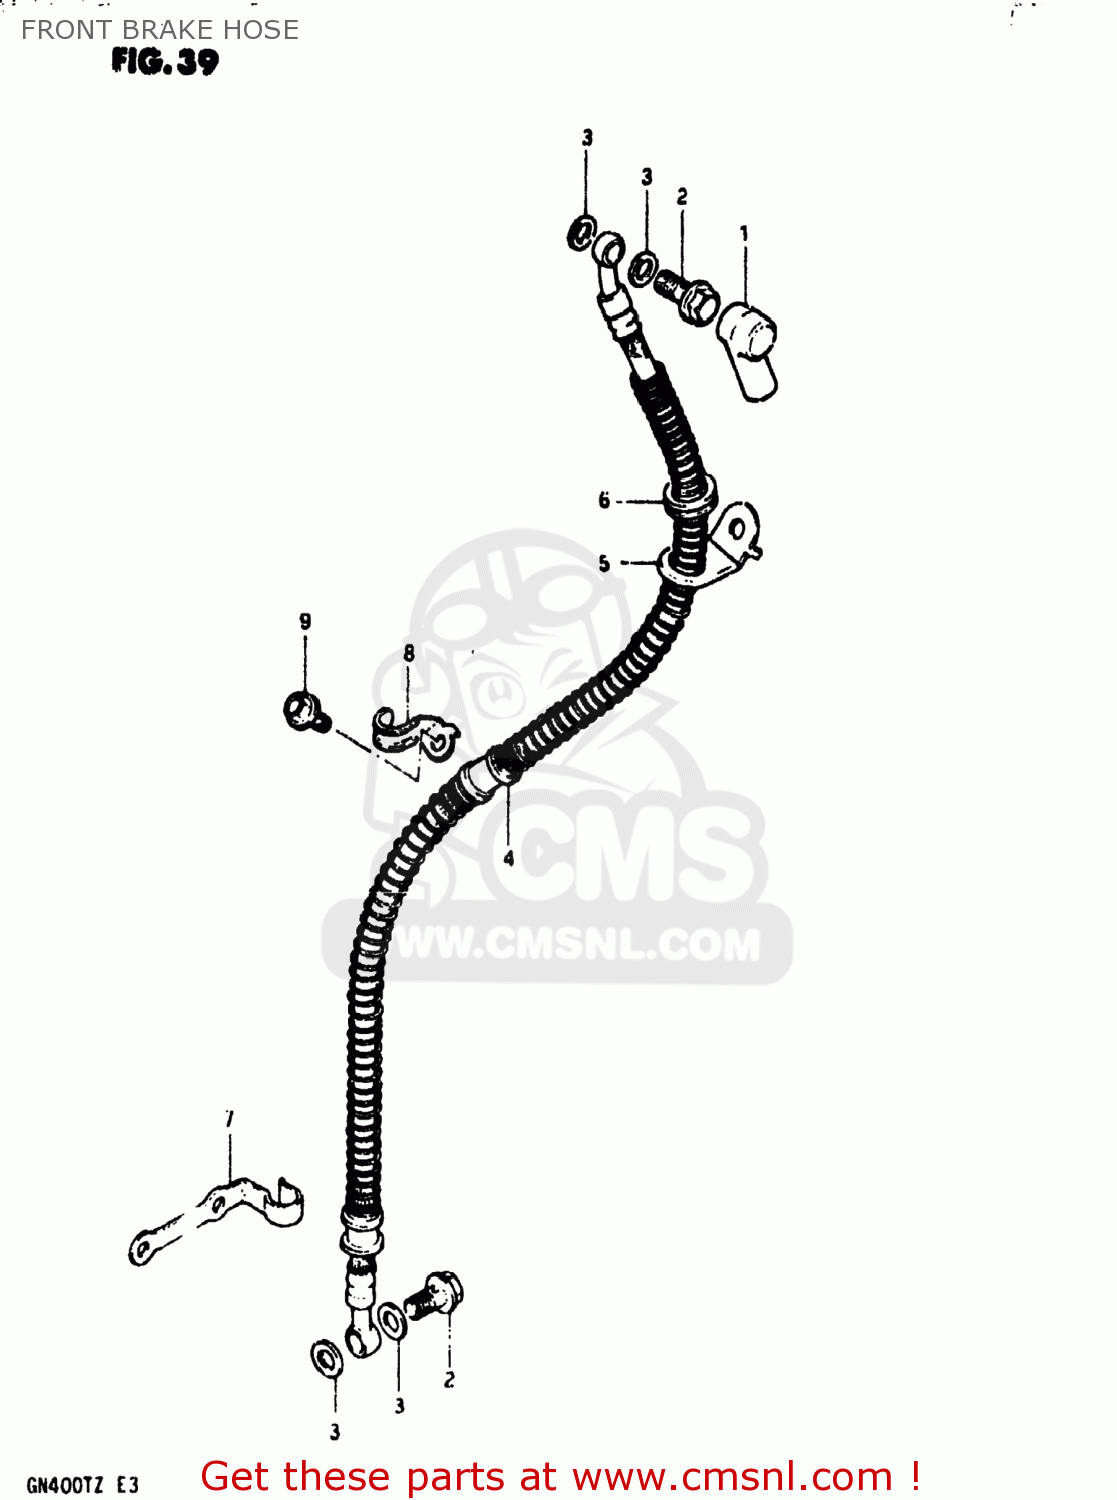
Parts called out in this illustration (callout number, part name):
1	BOOT,MASTER CYLINDER
2	BOLT,UNION
3	WASHER
4	HOSE,FRONT BRAKE
5	GUIDE,BRAKE HOSE
6	GROMMET
7	GUIDE,BRAKE HOSE NO.2
8	GUIDE,BRAKE HOSE NO.3
9	BOLT
